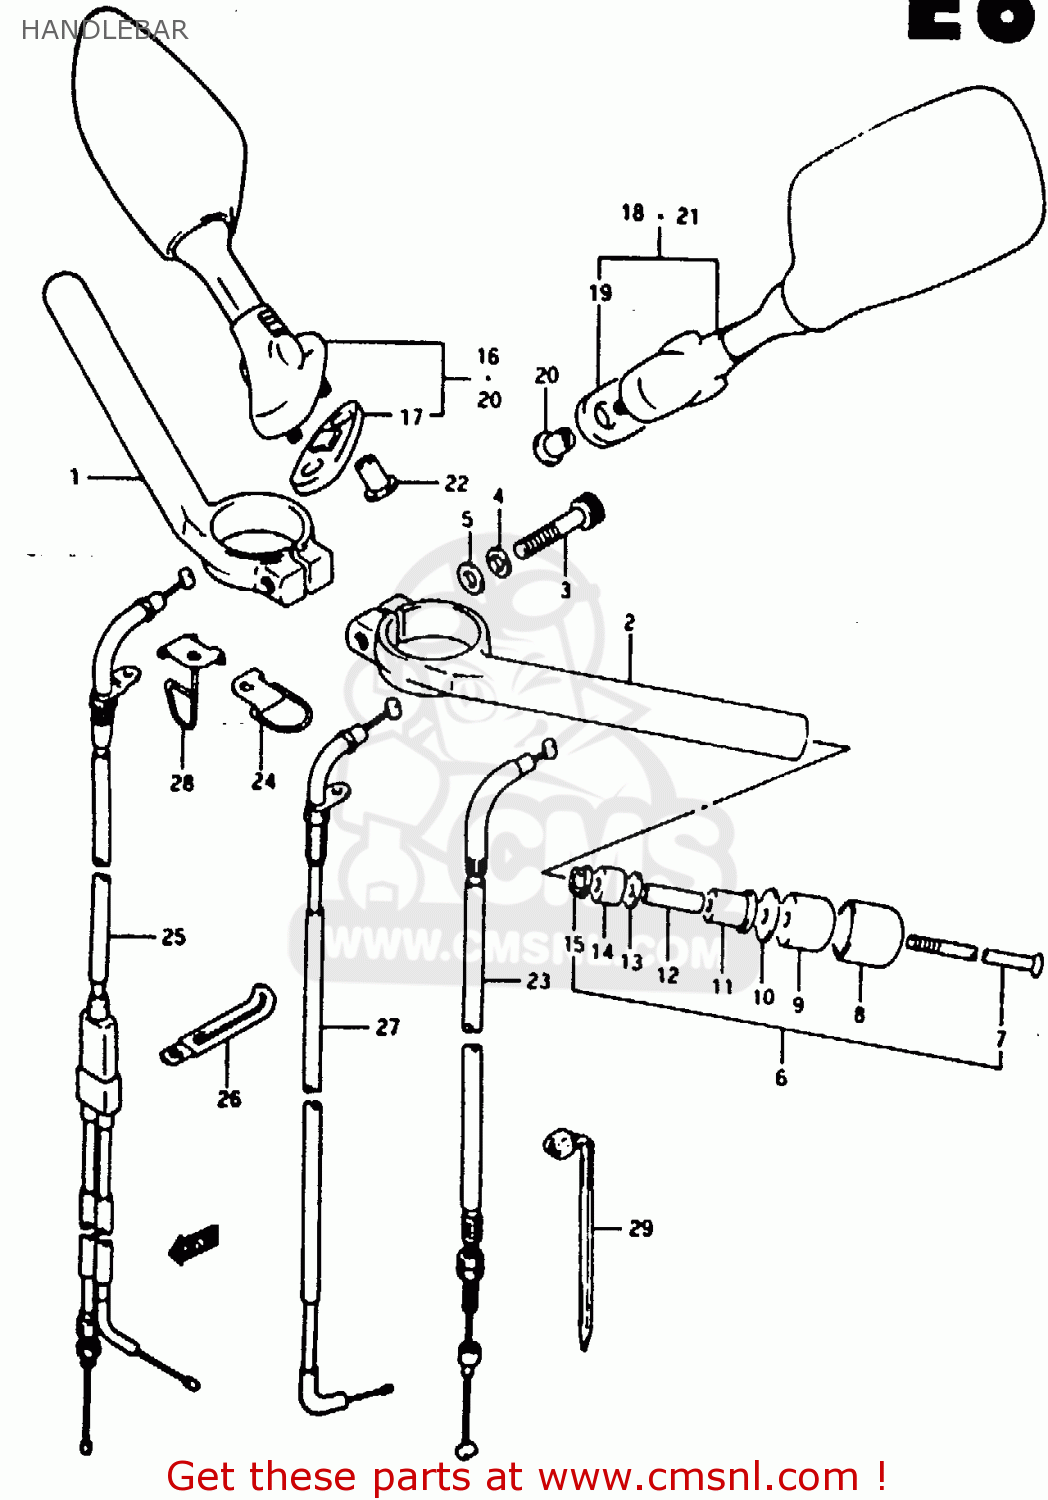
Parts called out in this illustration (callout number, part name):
1	HANDLEBAR,R
2	HANDLEBAR,L
3	BOLT
4	LOCK WASHER
5	WASHER
6	BALANCER SET, HANDLEBAR
7	SCREW(6X127)
8	CAP
9	BALANCER,HANDLE
10	SPACER,BALANCER
11	EXPANDER,HANDLE BALANCER
12	SPACER,EXPANDER
13	WASHER
14	EXPANDER,HANDLE
15	NUT
16	MIRROR ASSY, REAR VIEW RH (BLACK)
17	GASKET,RR VIEW MIRROR,R (NAS)
18	MIRROR ASSY,RR VIEW,L
19	GASKET,RR VIEW MIRROR,L (NAS)
20	MIRROR ASSY, REAR VIEW RH (BLACK)
21	MIRROR ASSY,RR VIEW,L
22	NUT,RR VIEW MIRROR
23	CABLE,CLUTCH
24	GUIDE, CLUTCH CABLE
25	CABLE ASSY,THROTTLE
26	CLAMP
27	CABLE,STARTER
28	GUIDE,STARTER CABLE
29	CLAMP(L:125)
